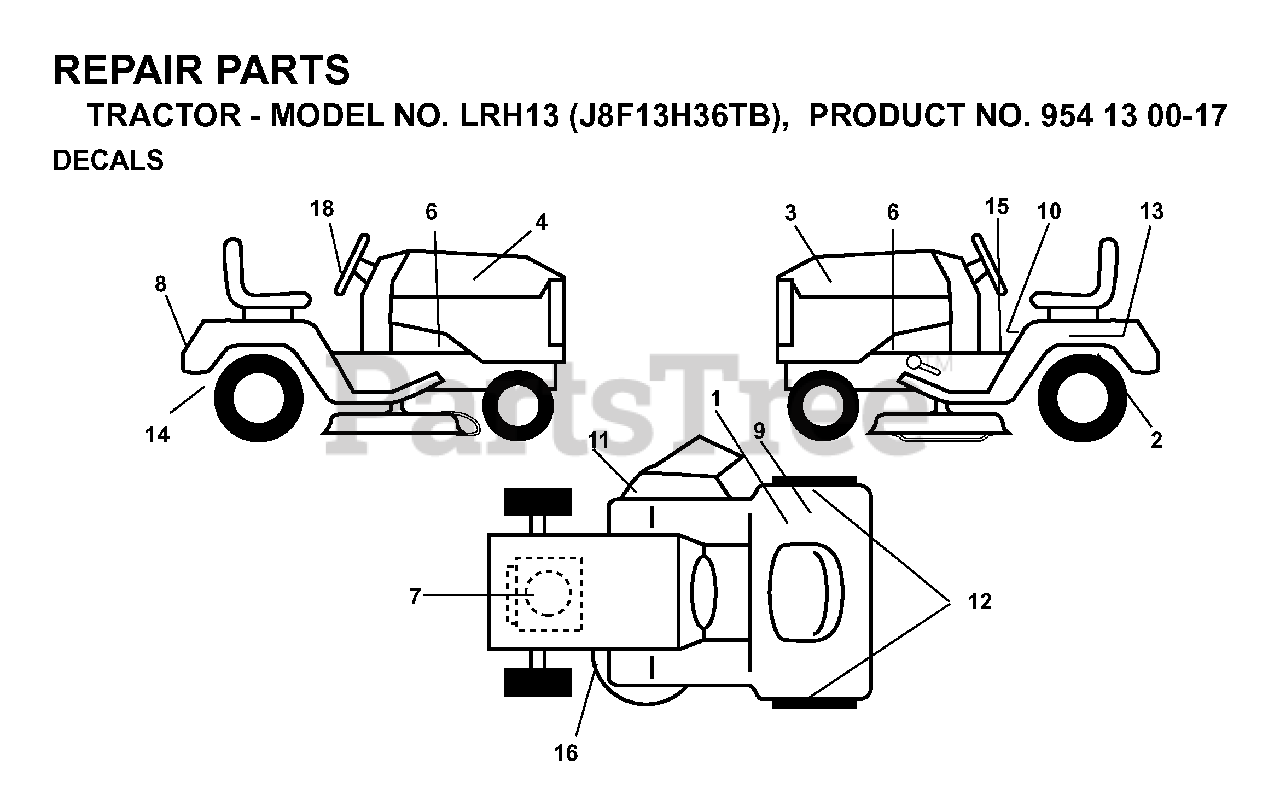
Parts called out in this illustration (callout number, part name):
1	DECAL EUROPE STANDARD CE
7	DECAL HP ENGINE
9	DECAL CERTIFICATION
10	DECAL READ OWNER'S MAN SYMS
11	DECAL MOWER CUT/FINGER
13	DECAL BTRY SYMBOLS
16	DECAL
